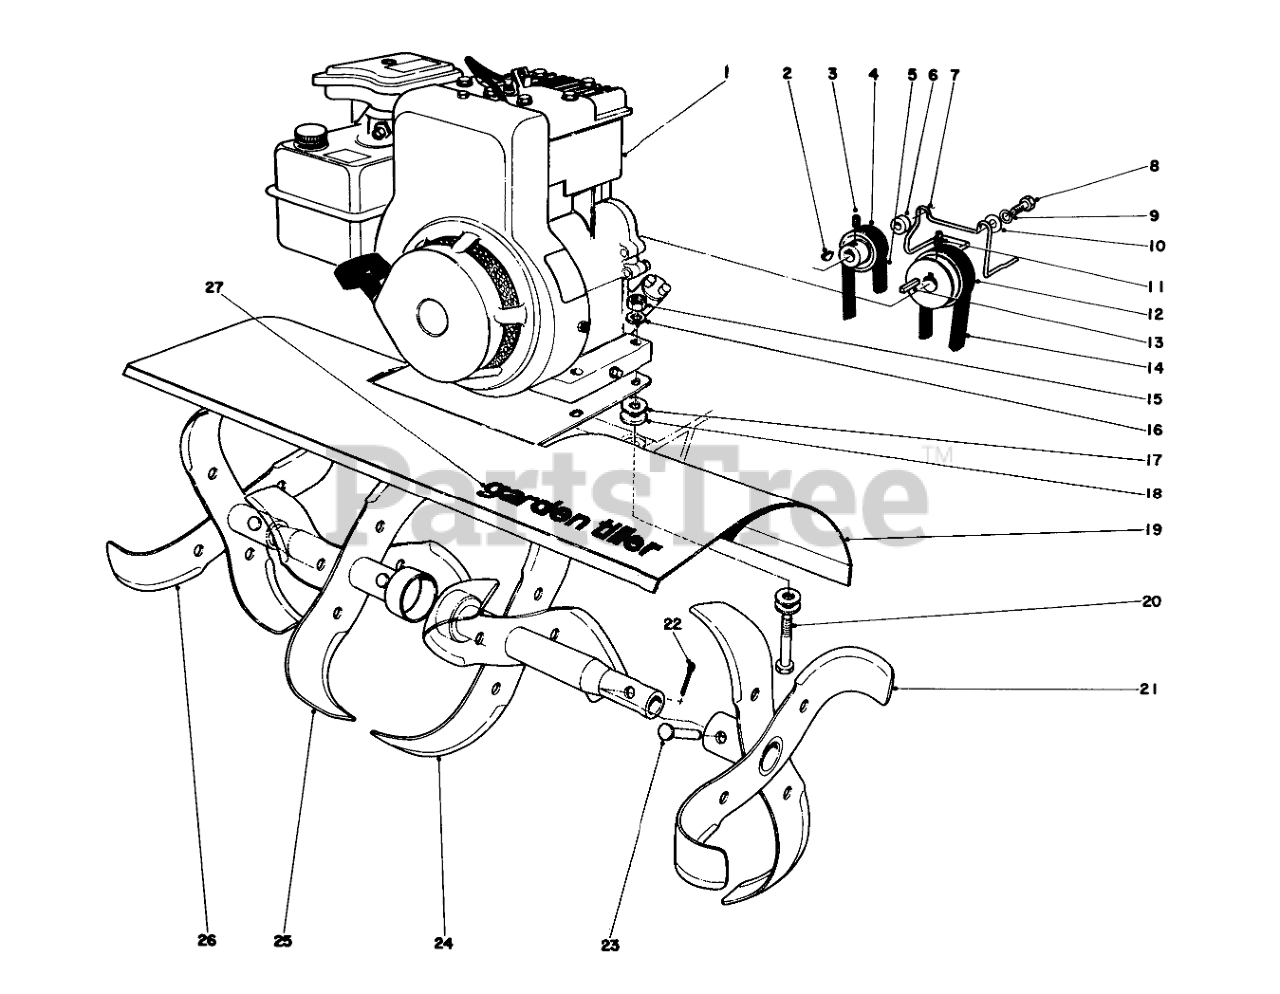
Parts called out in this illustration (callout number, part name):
1	Engine
2	KEY-WOODRUFF
3	SCREW-SET
4	Pulley
5	V-BELT
6	SPACER
7	BELT GUIDE
8	SCREW-HH
9	WASHER-LOCK
10	WASHER-FLAT
11	SCREW-SET, HSH
12	Engine Pulley
13	KEY-SQUARE
14	Belt
15	NUT-HEX
16	WASHER-LOCK
17	WASHER-FLAT
18	WASHER-FLAT
19	Shield
20	SCREW-HH
21	LH OUT SLASH TINE WA
22	PIN-COTTER
23	TINE PIN
24	Inner Tine L.H.
25	Inner Tine R.H.
26	RH OUT SLASH TINE EA
27	Decal
